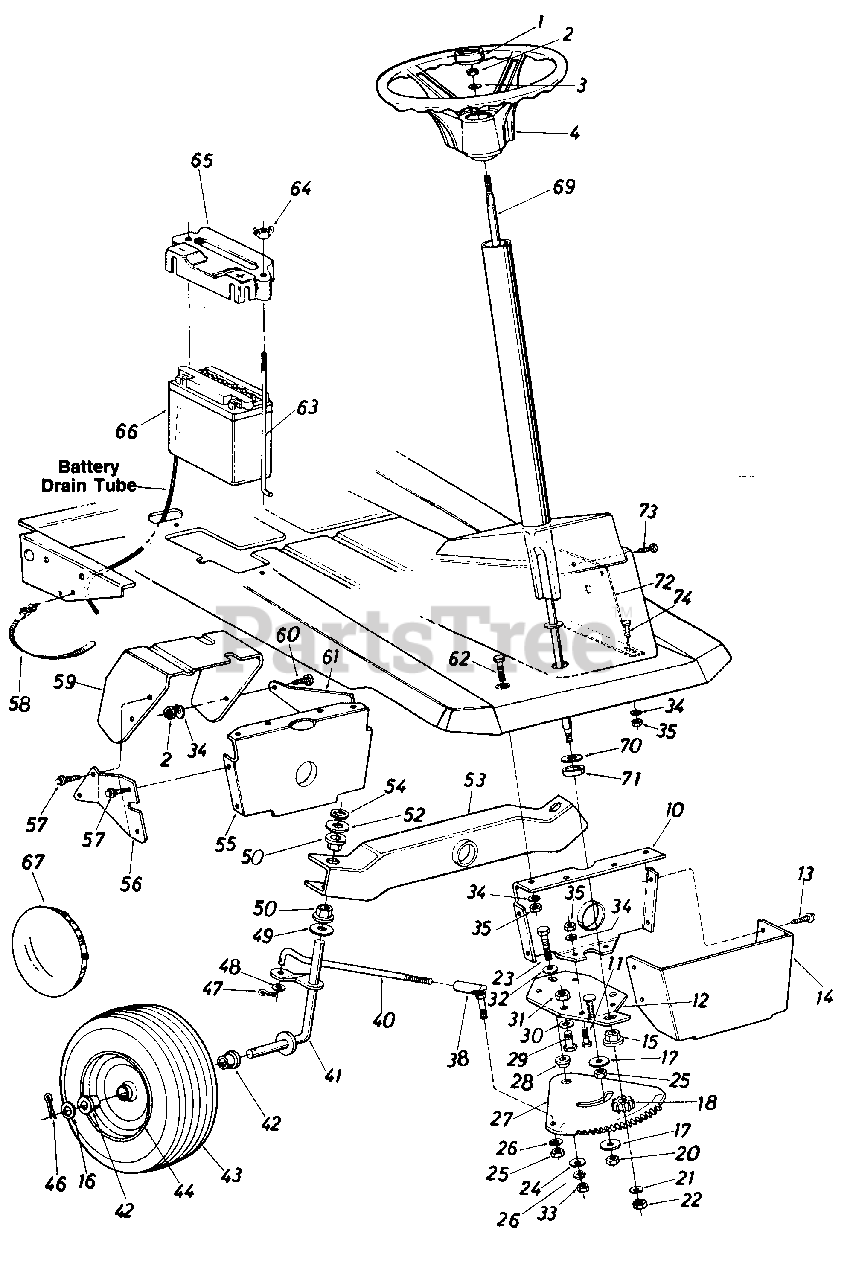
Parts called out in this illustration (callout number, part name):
1	Steering Wheel Cap
2	Hex L-Nut 5/16-24 Thd.
3	Bell-Wash. .345" I.D. x .88" O.D.
4	Steering Wheel Ass'y.
10	Pivot Bar Bracket
11	Hex Bolt 5/16-18 x .75" Lg.
12	Steering Gear Support Brkt.
13	Hex Wash. Hd. AB-Tap Scr. 1/4 x.62" Lg.
16	Fl Wash .64" I.D. x 1.5" O.D.
17	Fl-Washer 3/8" I.D. x 1.37" O.D.
18	Steering Pinion Gear
20	Hex L-Nut 3/8-24
21	Fl-Wash. .34" I.D. x .68" O.D.
22	Hex Nut 5/16-24 Thd.
23	Hex Bolt 3/8-24 x 1.25" Lg. (Grade 5)
24	Fl-Wash. .385" I.D. x 1.38"
25	Hex Nut 3/8-24 Thd.
26	L-Wash. 3/8" I.D.
27	Steering Gear Segment
28	Shoulder Spacer .622" Dia. x .21 8
29	Hex Bolt (Nylon) -1/2-13 x .75"
30	Fl-Wash. .530" l.D. x .930"
31	Hex Nut 1/2-13 Thd.
32	Bell-Wash. .385" I.D. x .88"
33	Hex Nut 3/8-24 Thd.
34	L-Wash. 5/16" I.D.
35	Hex Nut 5/16-18 Thd.
38	Ball Joint Ass'y. 3/8-24 Thd.
40	Steering Tie Rod
41	Front Axle Ass'y.-R.H.
42	Flange Bearing .632" I.D.
43	Front Wheel Ass'y. Comp.
44	Front Wheel Rim Only
46	Cotter Pin 1/8" Dia. x 1.25"
47	Cotter Pin 1/8" Dia. x 1.00"
48	Fl-Wash. .385" I.D. x 87n
49	Fl-Wash. .635" I.D. x 1.24n
50	Hex Flange Bearing
52	Fl-Wash. .635" I.D. x 1.12"
53	Pivot Bar Ass'y.
54	Speed Nut S18n l.D.
55	Pivot 8ar Bracket
56	Bracket Reinforcement-R.H.
57	Hex Wash. Hd. AB-Tap Scr. 1/4 x .62" Lg.
58	Cable Tie
59	Clutch-Brake Pedal Ass'y.
60	Hex Bolt 5/16-18 x .75" Lg.
61	Bracket Reinforcement-L.H.
62	Hex Bolt 5/16-18 x 75" Lg.
63	Battery Hold Down Rod
64	Wing Nut Solid 1/4-20 Thd.
65	Battery Hold Down Cover
66	12V Battery
67	Chrome Hub Cap
69	Steering Shaft Ass'y.
70	Fl-Wash. .62" l.D. x 1.25" O.D.
71	Spacer (Plastic)
74	Hex Bolt 5/16-18 x 2.00" Lg.
